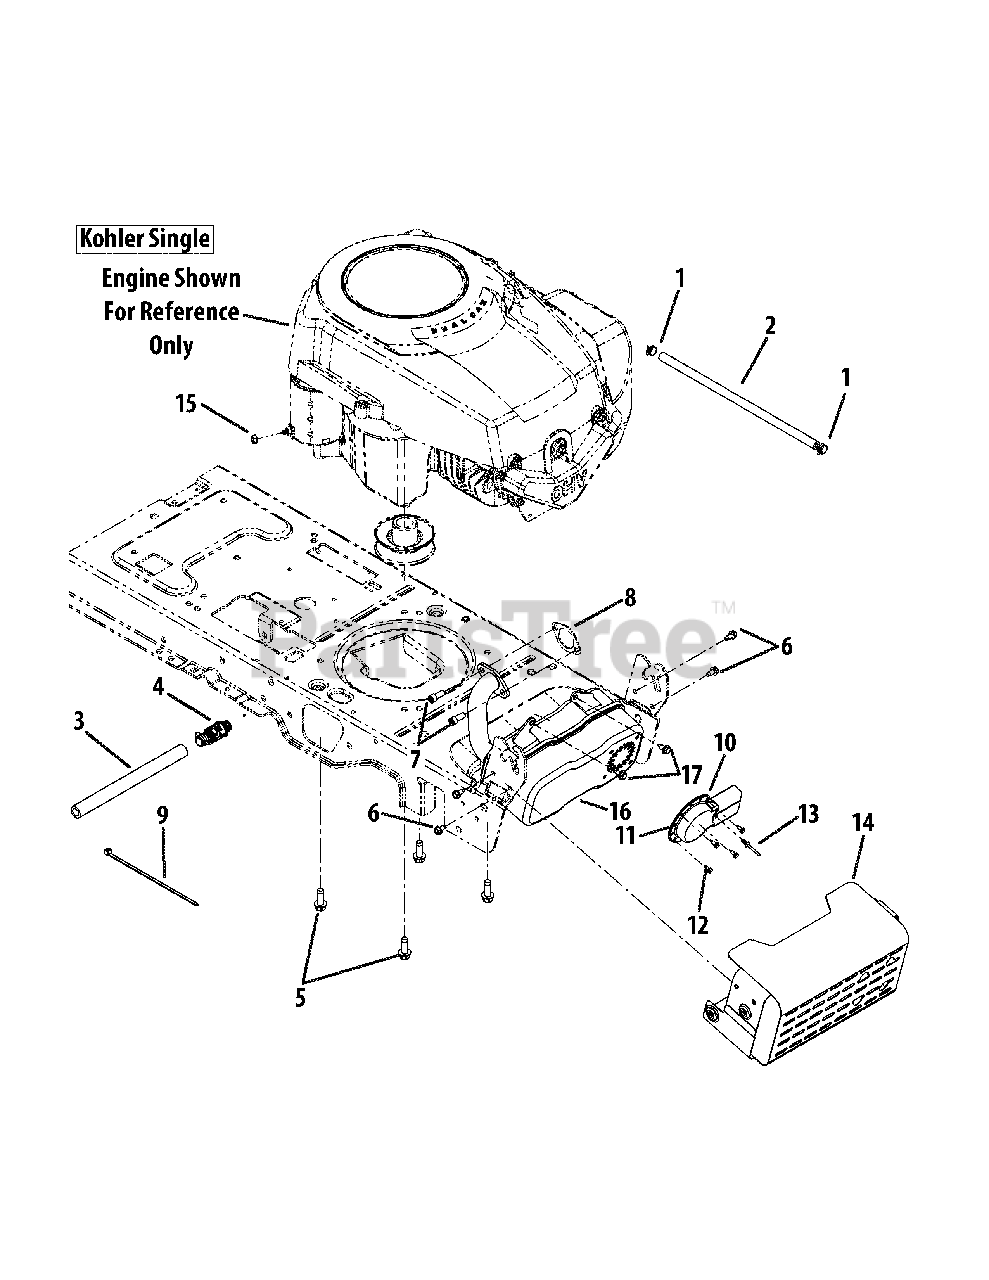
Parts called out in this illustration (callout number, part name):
1	Hose Clamp
3	Extension Hose
5	Hex Washer Screw, 3/8-16 x 1.00
6	Hex Washer Screw, 1/4-20 x .500
7	Screw, 5/16-18 x .750
8	Exhaust Gasket
9	Cable Tie, 3/16 x .05 x 7.4
10	Muffler Deflector
11	Long Muffler Deflector
12	Hex Washer Screw, #8-18 x .500
13	Rivet, .188 x .300
14	Muffler Shield Assembly
15	Sems Nut, 1/4-20
16	Kohler Single Muffler
17	Hex Washer Screw, 1/4-20 x .625
